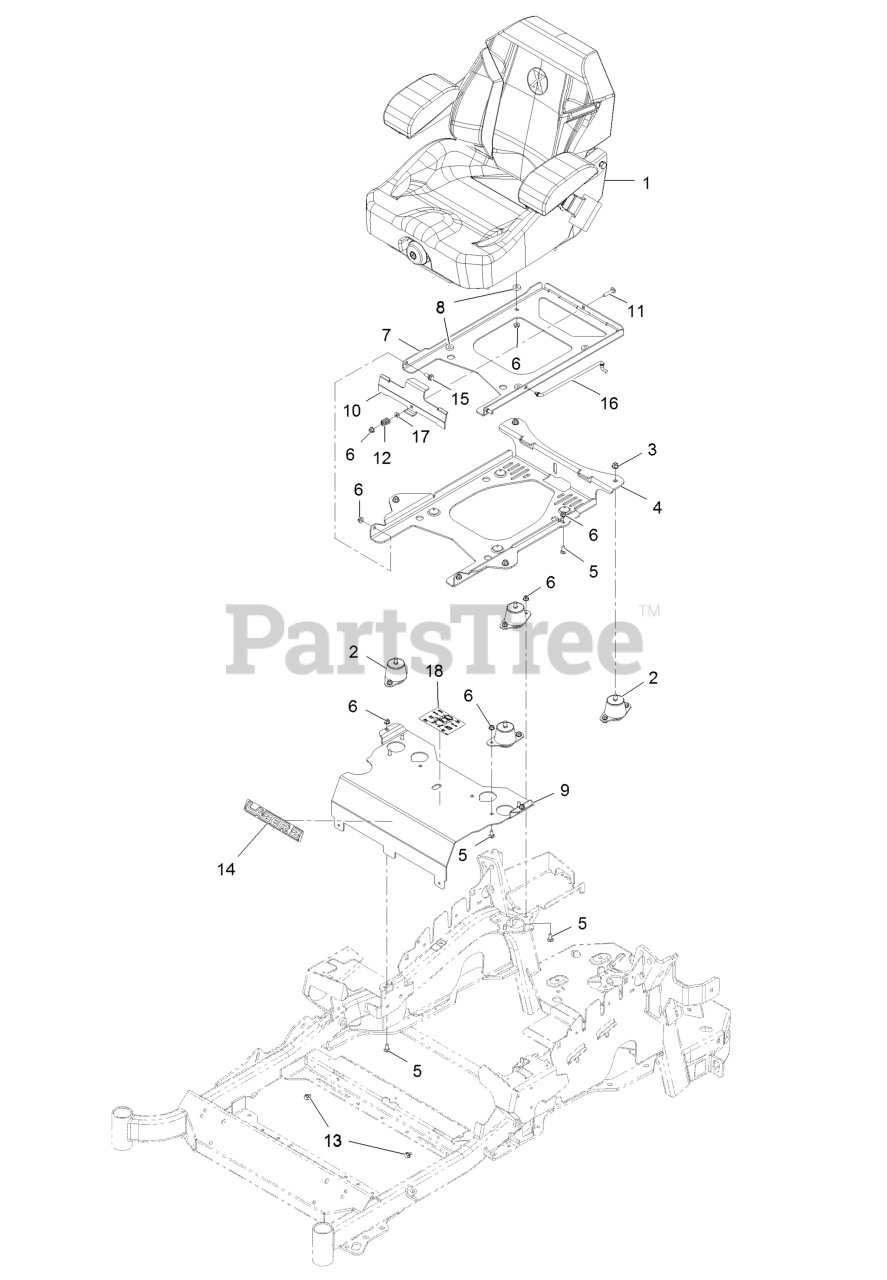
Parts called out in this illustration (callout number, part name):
1	Kit-Suspension Seat
2	Isolator-Seat
3	Nut-Nyloc 3/8-16 Flg
4	Plate-Tilt, Seat Support
5	Bolt-Carriage 5/16-18 X 3/4 Short Neck
6	Nut-Nyloc 5/16-18 Flg
7	Plate-Frame, Seat
8	Spacer-Pin, Mounting
9	Panel-Front, Seat Mount
10	Plate-Latch, Seat
11	Bolt-Carriage 5/16-18 X 1 1/2
12	Spring-Compression
13	Screw-HWH 5/16 X 1/2 Tf
14	Decal, Lazer Model
15	Screw-Shoulder
16	Rod-Prop
17	Washer-5/16 SAE
18	Decal-Service Aid
